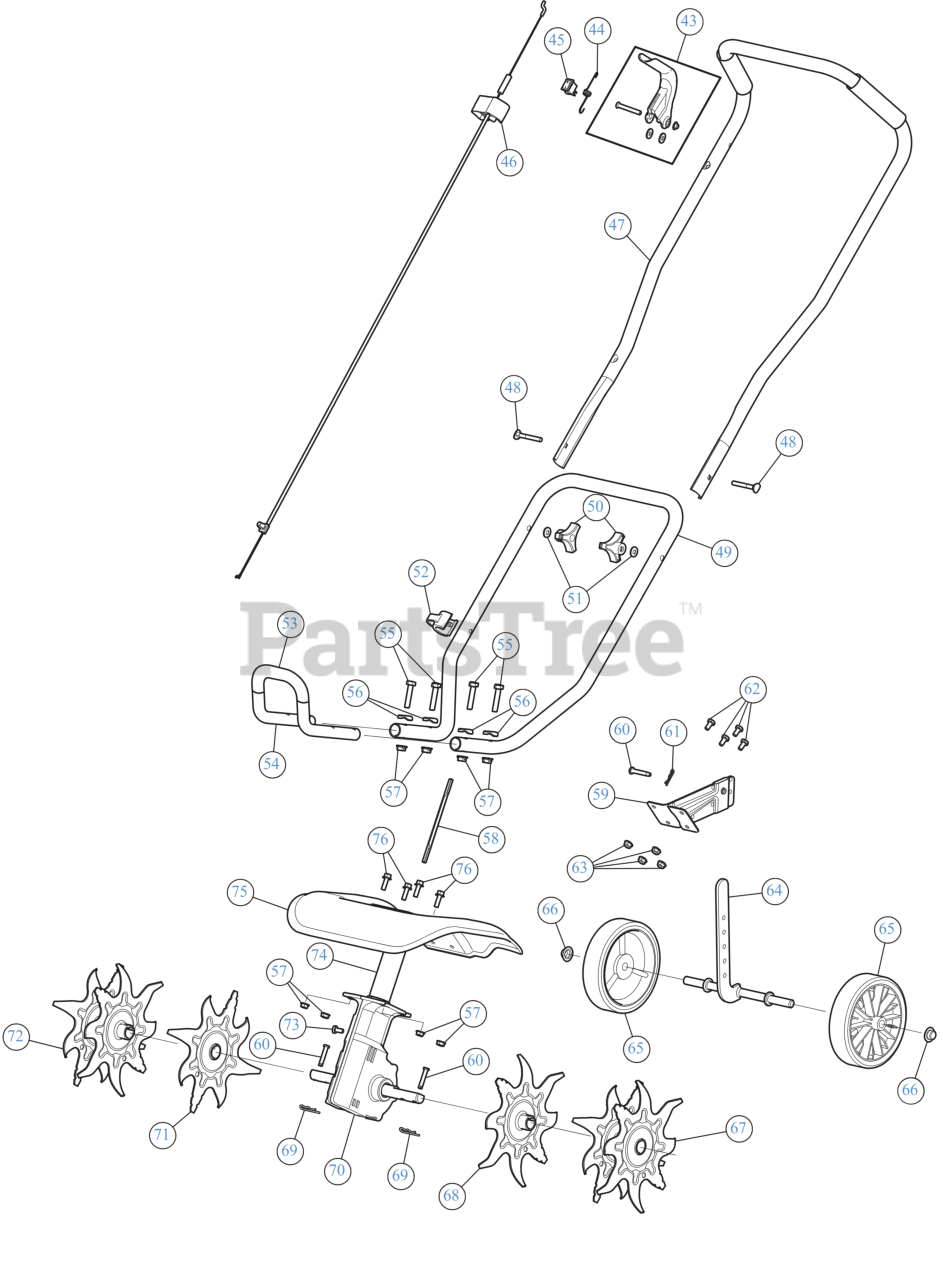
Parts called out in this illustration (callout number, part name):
43	THROTTLE LEVER
44	SPRING
45	SW, MOMENTARY ON/O
46	THROTTLE CABLE
47	HANDLE UPR CULT
48	BOLT, CARRIAGE CRV
49	LOWER HANDLE
50	KNOB, 3-PRONG ¼ "-
51	WASH, FLAT SPECIAL
52	CABLE GUIDE
53	FOAM GRIP - 9"
54	FRONT HANDLE
55	SCREW 5/16-18 x 1.5 LG
56	SADDLE WASHER
57	LOCK NUT 1/4
58	SHAFT-FLEX
59	TAILPIECE BRACKET ASSEMBLY
60	CLEVIS PIN
61	BOW TIE COTTER PIN 1/4-5/16
62	SCREW 1/4-20X.5 GR5
63	LOCK NUT 1/4
64	BRACKET ASSEMBLY
65	WHEEL 5-1.5 GRAY
66	PUSH CAP
67	TINE ASSEMBLY (LH)
68	TINE ASSEMBLY (LH)I (RH)O
69	BOW TIE COTTER PIN 1/4-5/16
70	GEARBOX ASSEMBLY CULT
71	TINE ASSEMBLY (LH)O (RH)I
72	TINE ASSEMBLY (RH)
73	SCREW 1/4-20 X.500
74	BOOM ASSEMBLY CULT
75	TINE SHIELD
76	HEX SCREW 1/4-20X.
